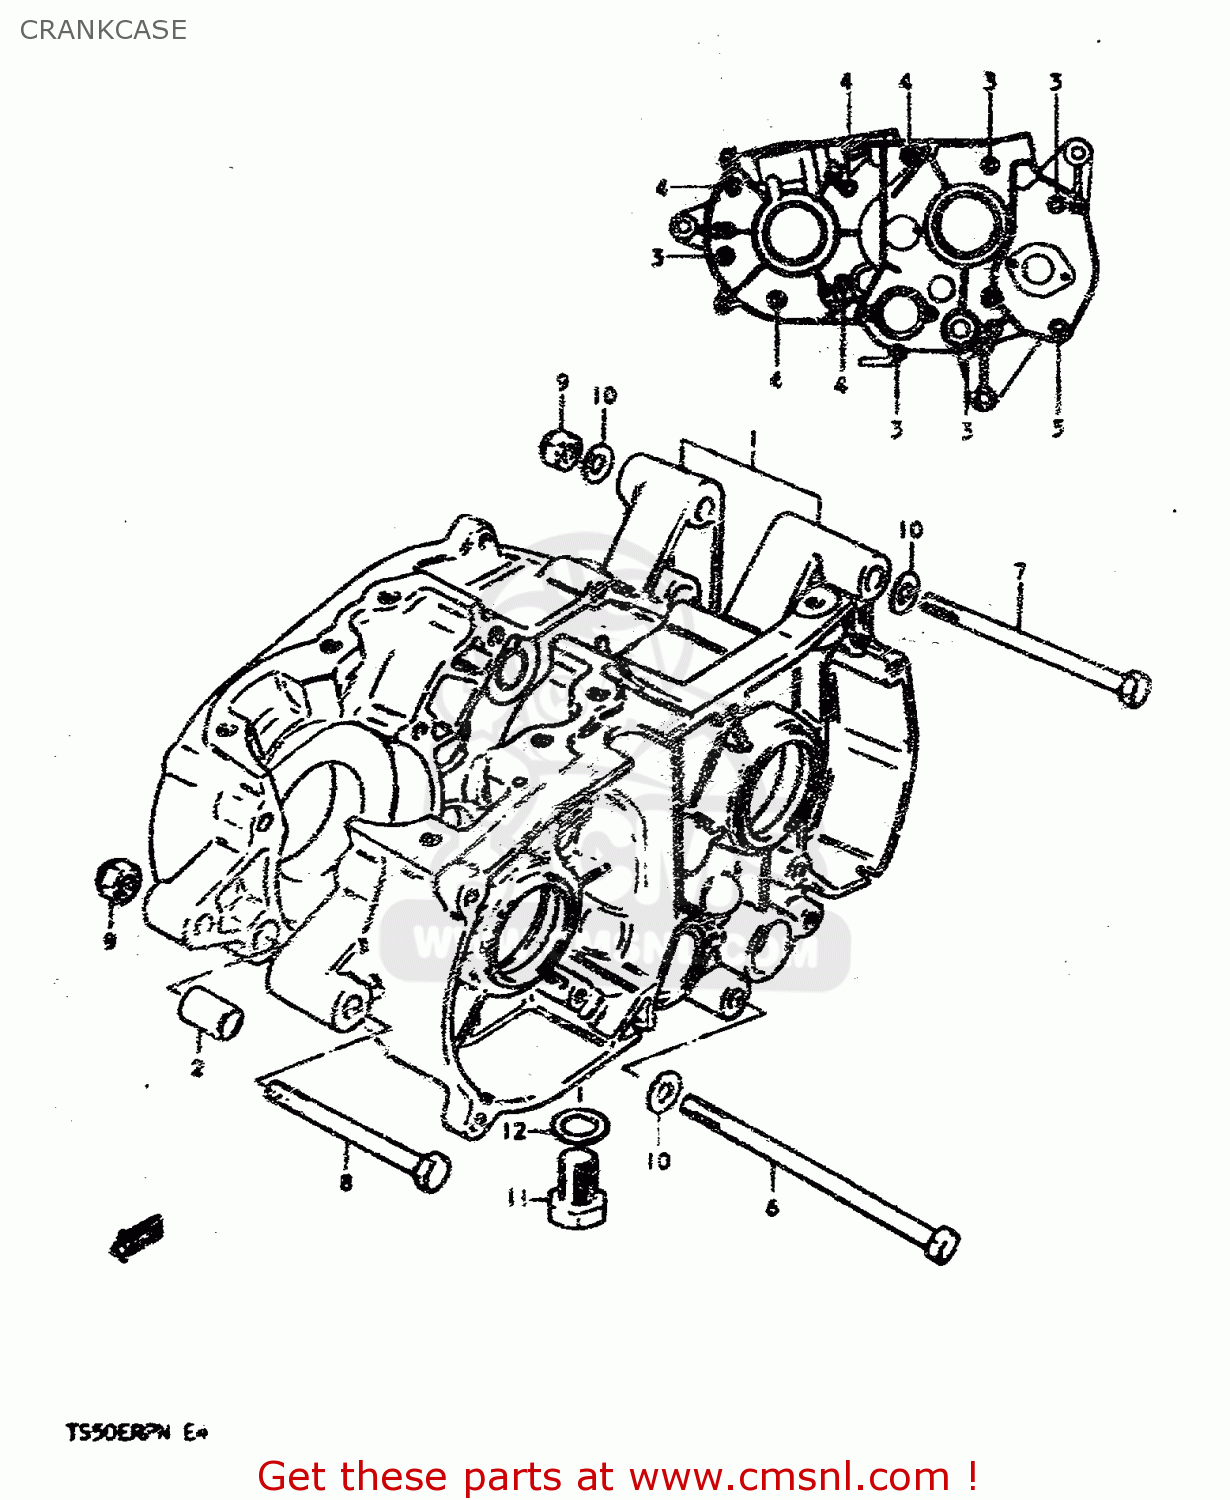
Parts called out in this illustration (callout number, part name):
1	CRANKCASE SET
2	PIN
3	SCREW (6X45)
4	SCREW (6X35)
5	SCREW
6	BOLT
7	BOLT
8	BOLT 8X75
9	NUT
10	WASHER
11	BOLT 10X20
12	GASKET(10X14X3.6) (NAS)
